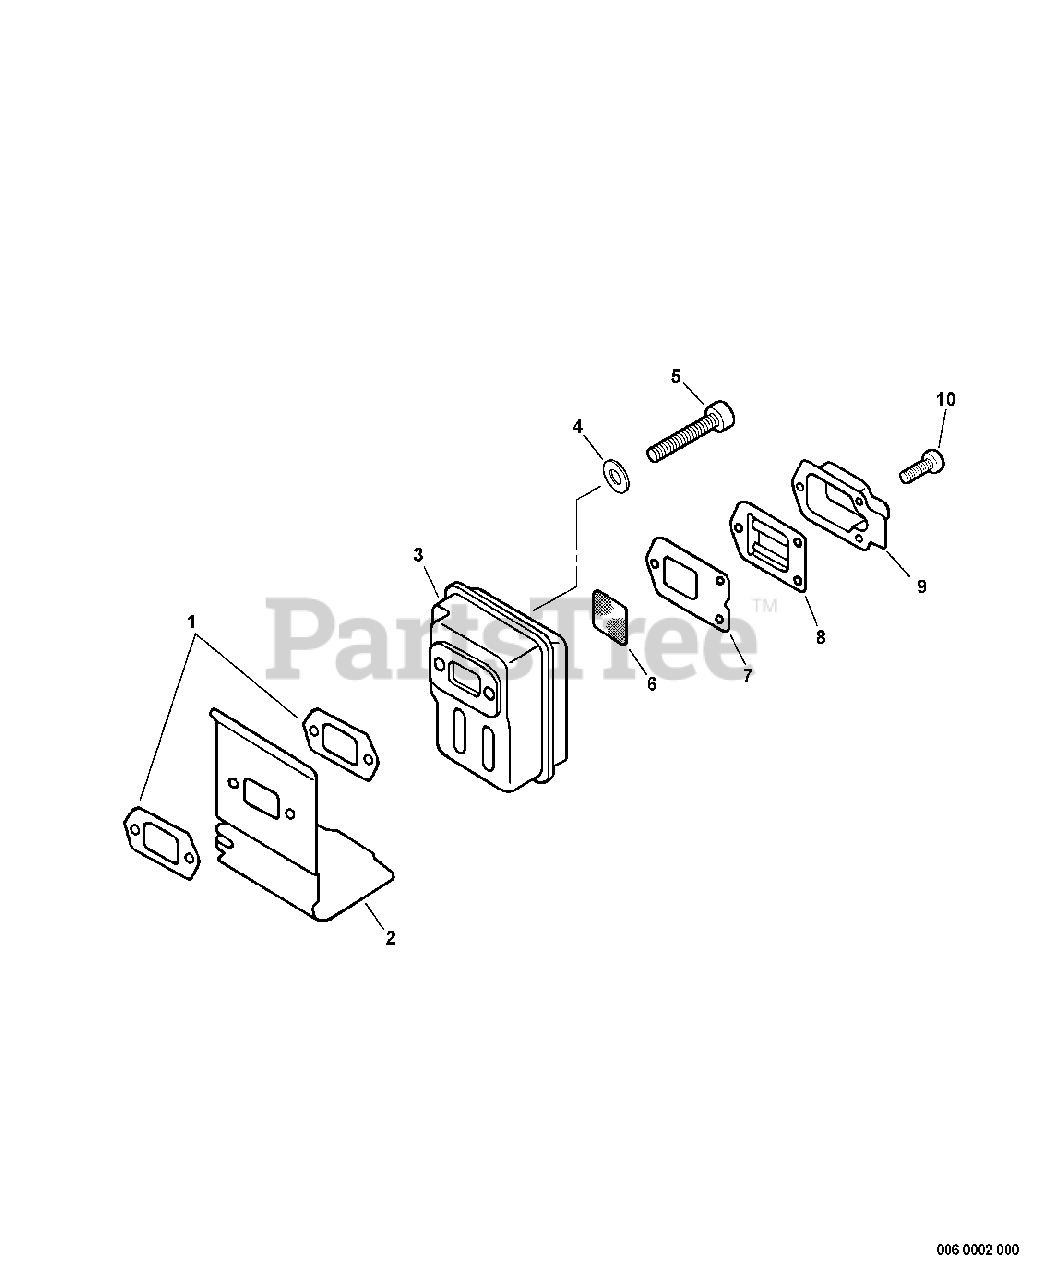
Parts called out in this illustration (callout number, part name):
1	GASKET, EXHAUST
2	HEAT SHIELD, EXHAUST
4	WASHER, FLAT 5.5×10×0.8
5	BOLT 5×55
6	SCREEN, SPARK ARRESTER
7	GASKET, EXHAUST
8	GUIDE, EXHAUST
9	GUIDE, EXHAUST - INNER
10	SCREW 4×10
